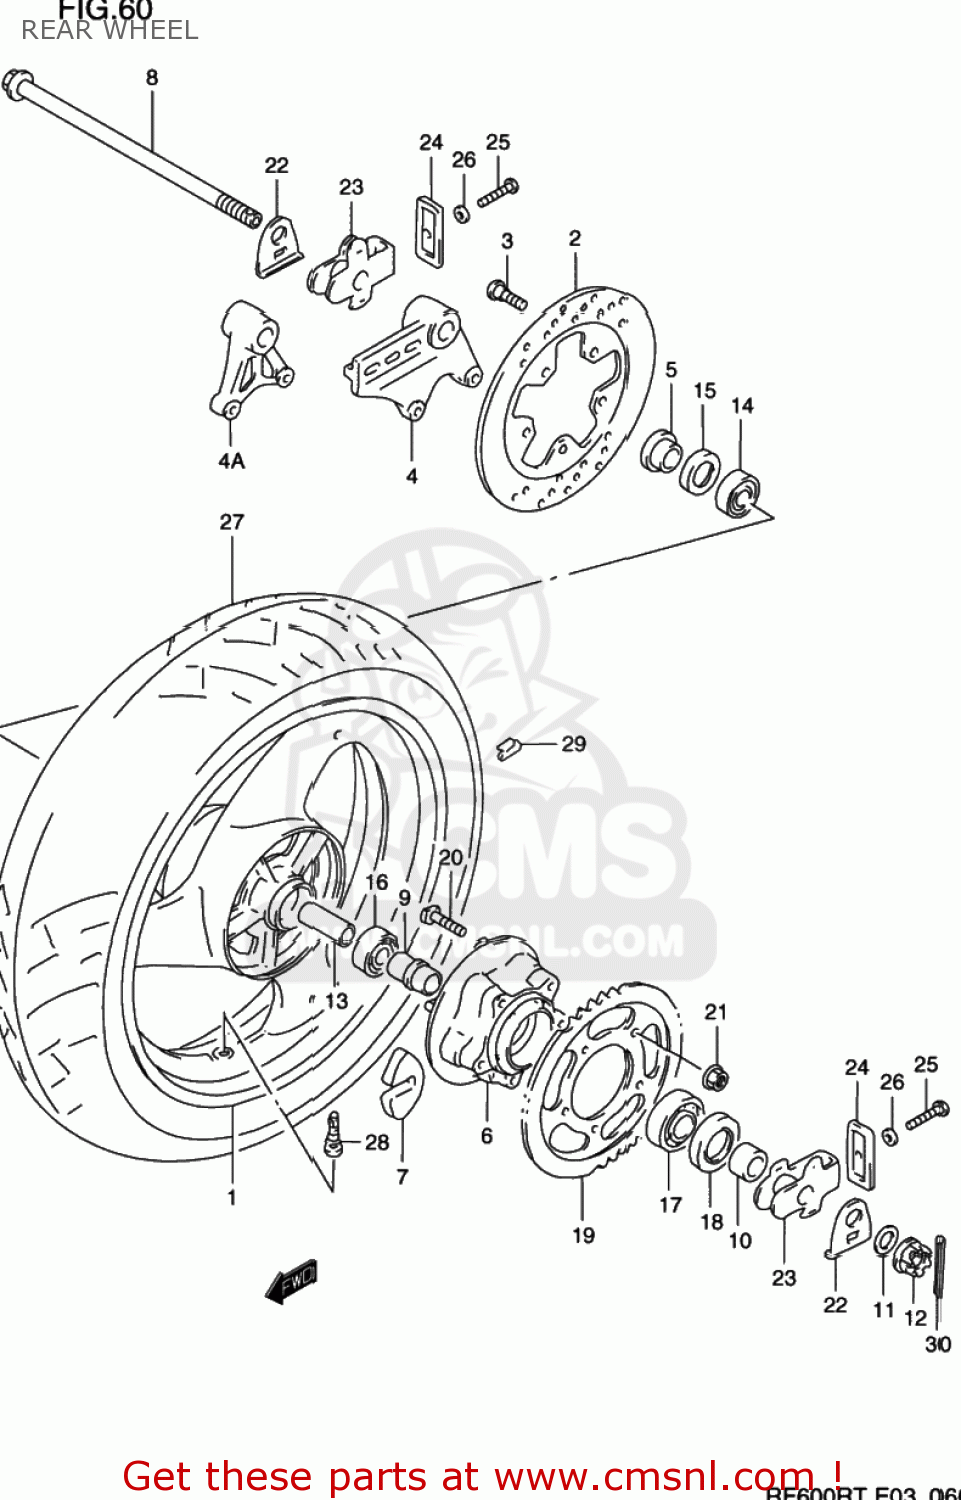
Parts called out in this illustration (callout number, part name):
1	WHEEL,RR(MT4.50X17)
2	DISC,RR BRAKE
3	BOLT 8X33
4	BRACKET,RR CALIPER
4A	BRACKET,RR CALIPER
5	SPACER,RR AXLE,R
6	DRUM,RR SPROCKET
7	ABSORBER,RR HUB SHOCK
8	AXLE,RR
9	RETAINER,RR HUB BEARING
10	SPACER,RR AXLE,L
11	WASHER (18.2X28X2.6)
12	NUT
13	SPACER(20.8X27.2X97)
14	BEARING
15	SEAL,OIL(28X47X7)
16	BEARING(20X47X14)
17	BEARING(25X62X17)
18	SEAL,OIL(35X62X8)
19	SPROCKET,RR(NT:43)
20	BOLT(10X47)
21	NUT
22	WASHER,CHAIN ADJUSTER
23	ADJUSTER,CHAIN
24	PLATE,CHAIN ADJUSTER GUIDE
25	BOLT(8X50)
26	WASHER
27	TIRE,REAR 160/70 ZR17
28	VALVE ASSEMBLY,WHEEL,TR412
29	BALANCER,WHEEL
30	PIN, COTTER
